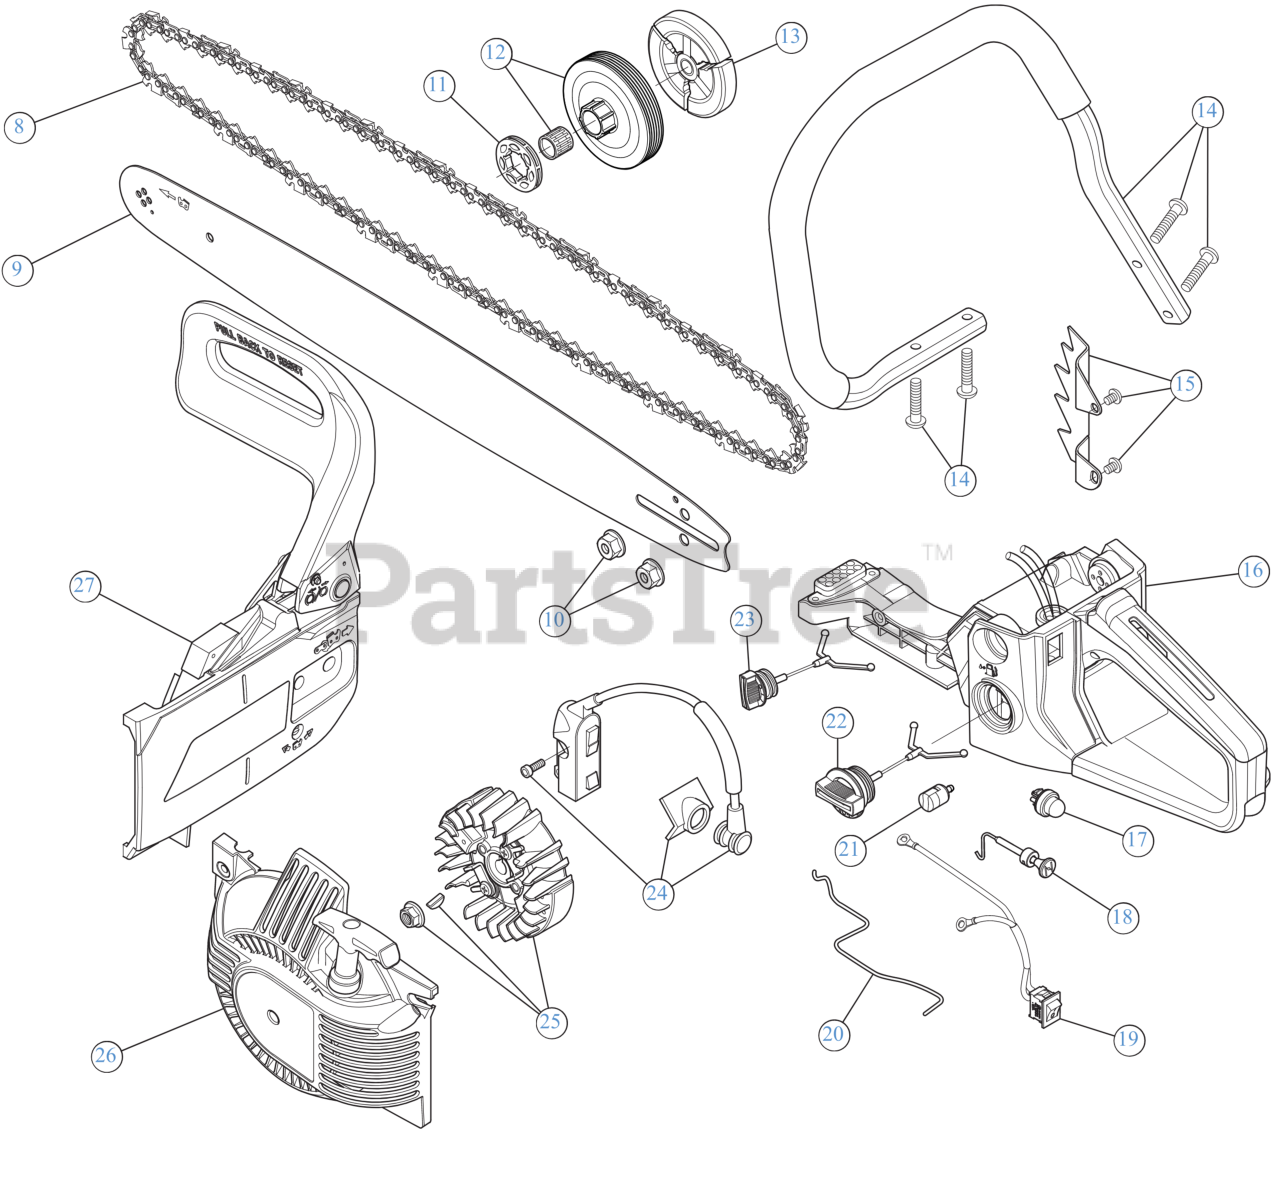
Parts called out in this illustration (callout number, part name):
8	20" CHAINSAW CHAIN
9	20" GUIDE BAR
10	BAR NUT M8
12	CLUTCH DRUM ASSEMBLY
13	CLUTCH ASSEMBLY
14	HANDLE ASSEMBLY
15	SPIKE PLATE W/HDW
16	FUEL HOUSING ASSEMBLY
17	PRIMER BULB YD2500-18410
18	CHOKE LEVER
19	SWITCH ASSEMBLY
20	THROTTLE ROD
21	FUEL FILTER YD4600-18034
22	FUEL CAP ASSEMBLY
23	OIL CAP ASSEMBLY
24	IGNITION MODULE
26	STARTING HOUSING
